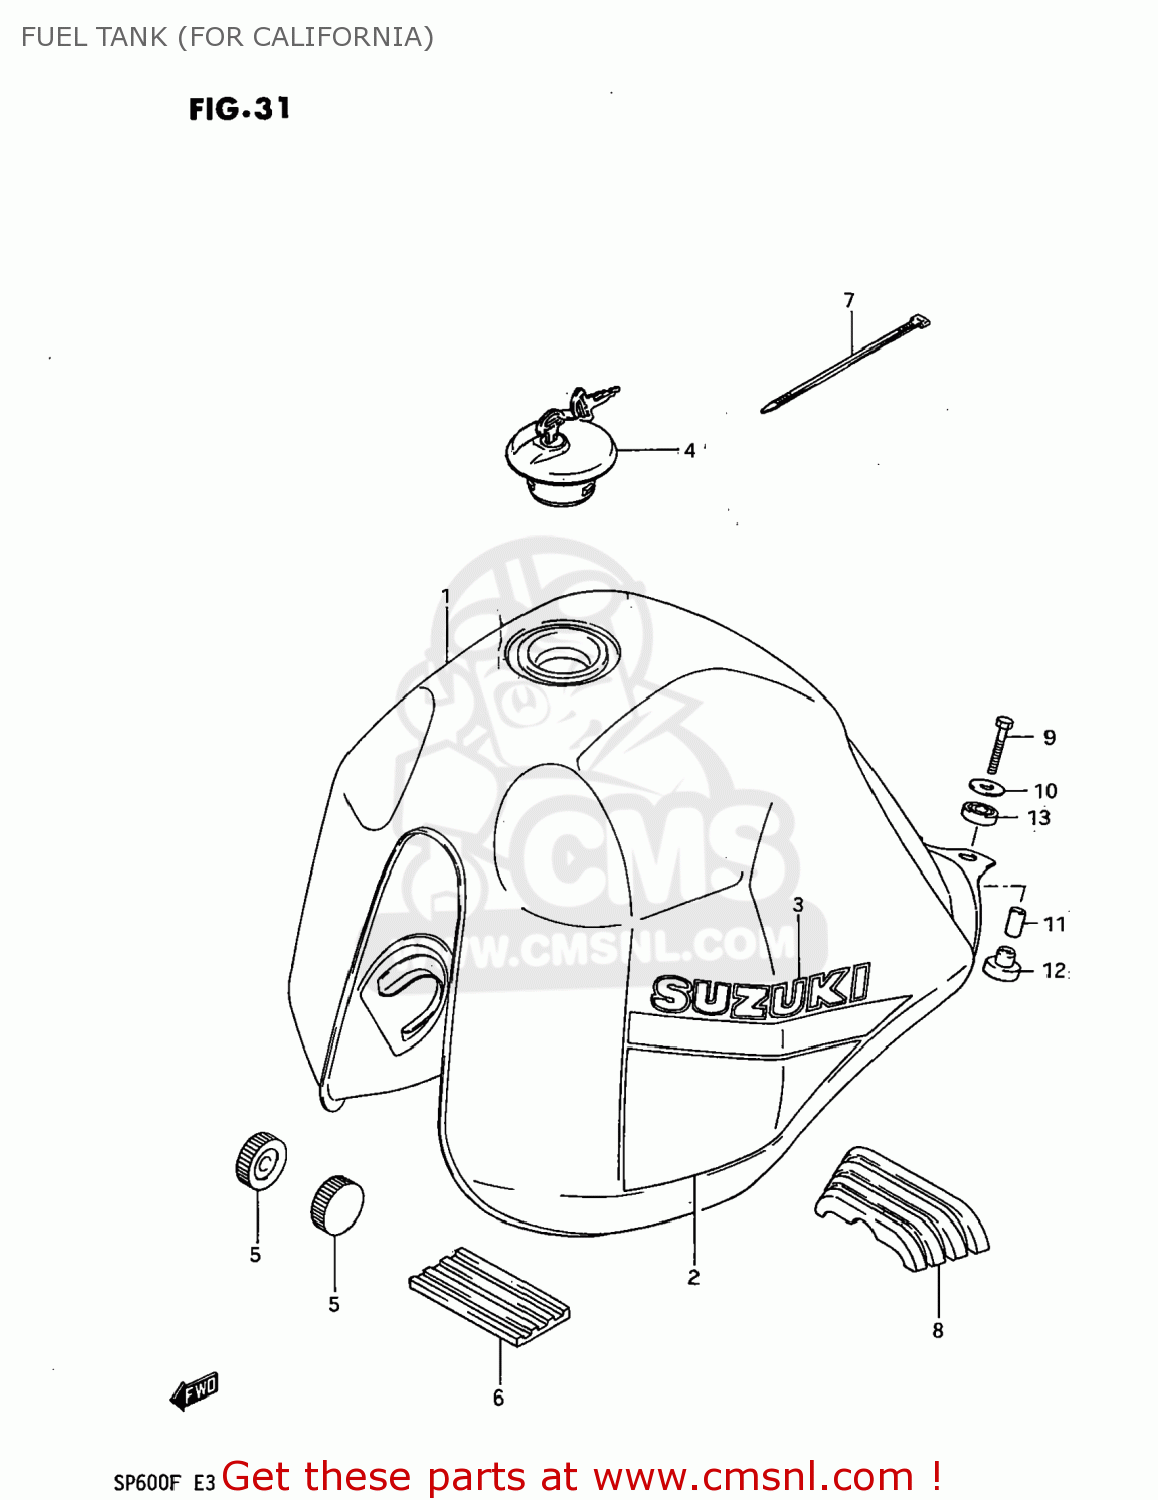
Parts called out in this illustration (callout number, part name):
1	TANK ASSEMBLY,FUEL
2	TAPE SET,FUEL TANK
3	EMBLEM
4	CAP SET,FUEL TANK
5	CUSHION
6	CUSHION,FUEL TANK UPR FR
7	CLAMP
8	CUSHION,FUEL TANK RR
9	BOLT
10	WASHER (6.5X24X1.6)
11	SPACER
12	CUSHION
13	CUSHION
